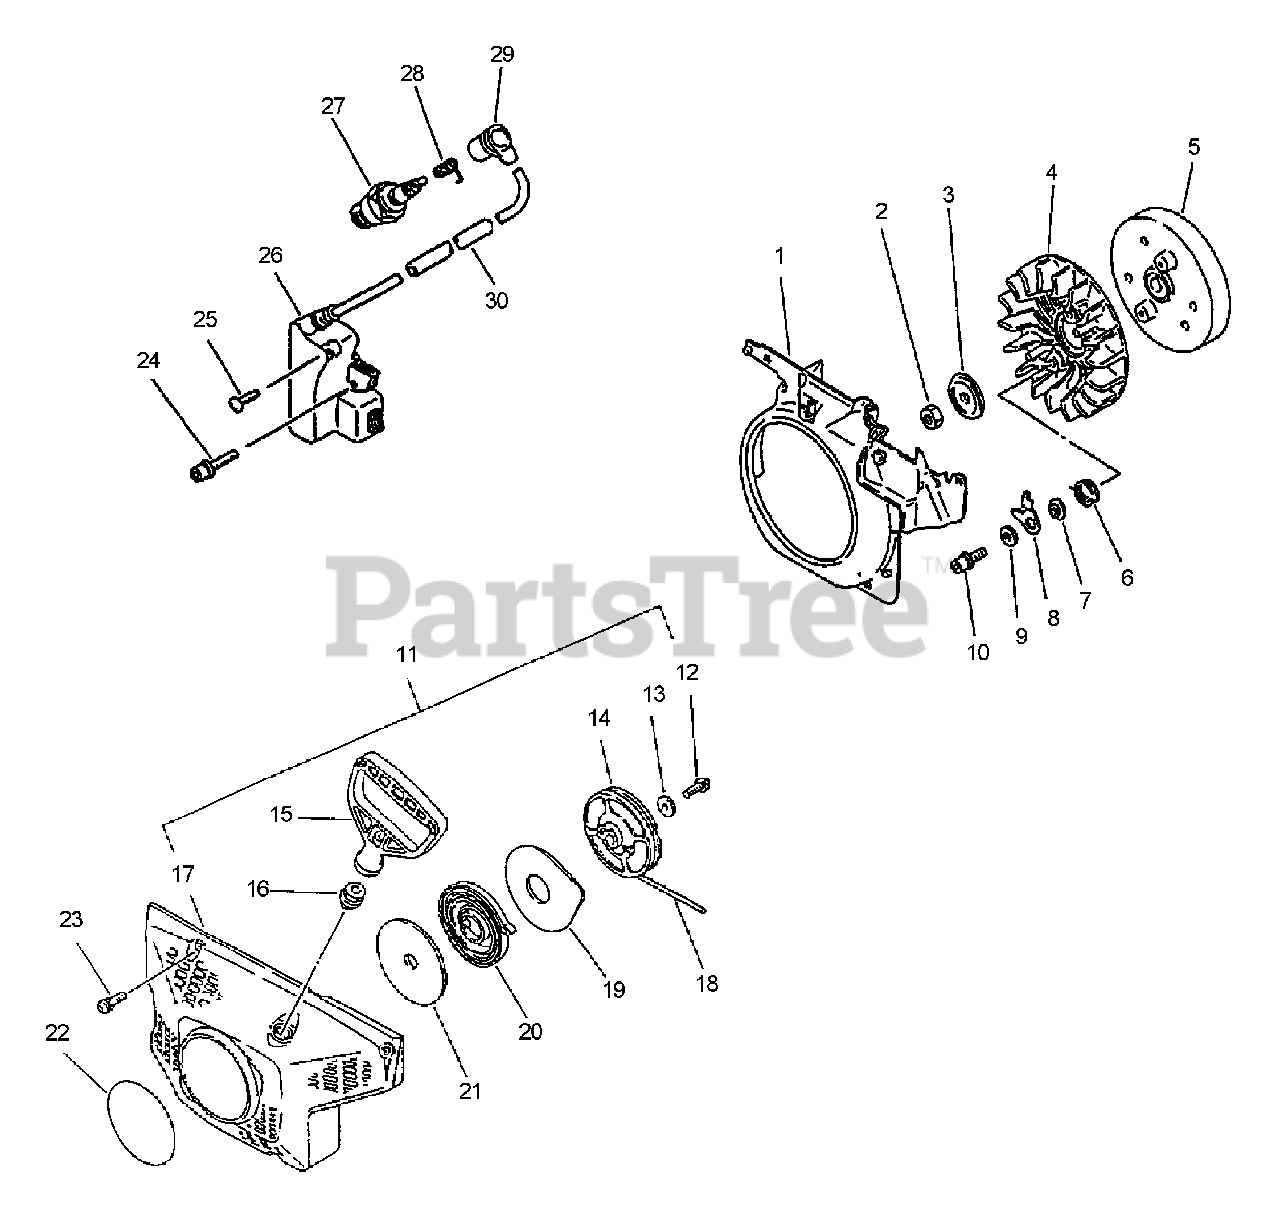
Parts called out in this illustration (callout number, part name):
1	SHIELD, FAN
3	WASHER 8.2×31×0.8
5	FLYWHEEL
6	SPRING, RETURN
7	SPACER, PAWL
8	PAWL, STARTER
9	WASHER 5.5×12×0.8
10	SCREW 5×20
11	STARTER ASSY
12	SCREW 5×14
13	WASHER 5.5×12×0.8
14	REEL, ROPE
15	GRIP, STARTER
16	GUIDE, ROPE
17	COVER, FAN
19	PLATE, STARTER
20	SPRING, RECOIL
21	PLATE, STARTER
22	LABEL - ECHO
23	BOLT 5×14
24	BOLT 4×20
25	SCREW 4×8
26	COIL, IGNITION
27	SPARK PLUG - CJ-6Y
28	TERMINAL, SPARK PLUG
29	CAP, SPARK PLUG
30	TUBE
